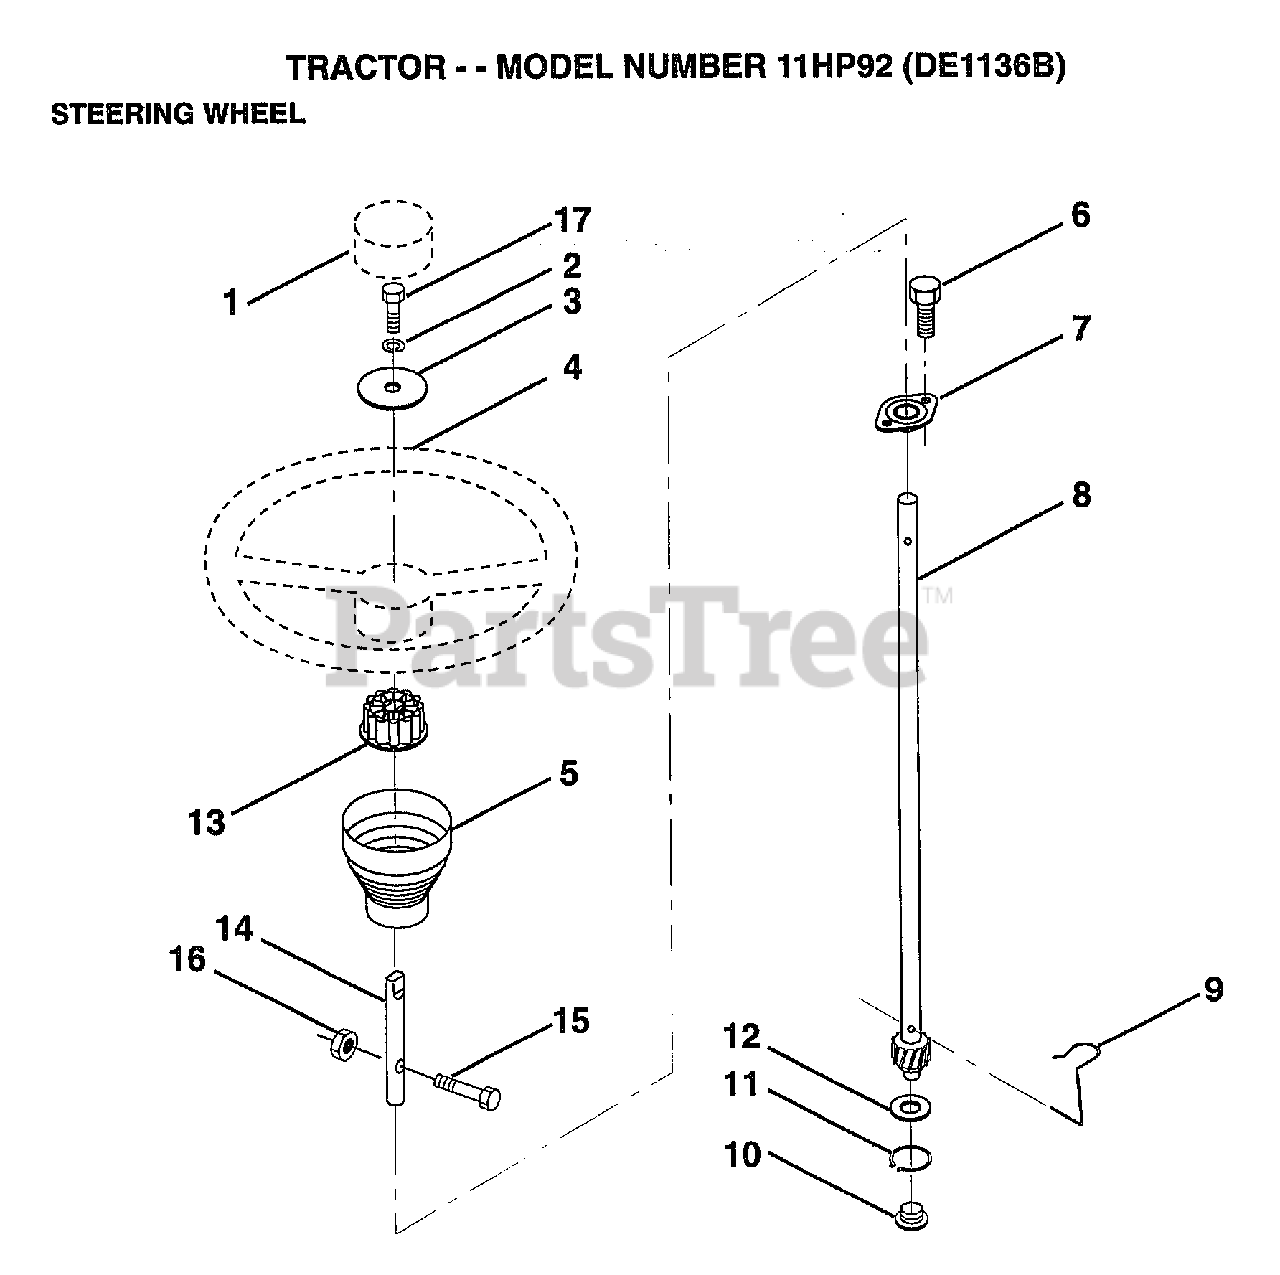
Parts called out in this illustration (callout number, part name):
1	CAP WHEEL STEER
2	LOCKWASHER
3	WASHER T
5	SLEEVE STEERING
6	"SCREW-TT,10-32 FL"
7	BUSHING.STR.623
8	SHAFT.STEERING.LR
9	STEERING CLIP
10	BUSHING STEER LWR
11	RING
12	WASHER LT
13	ADAPTER LT
14	EXT SHAFT STEERIN
15	BOLT
16	NUT
17	BOLT
